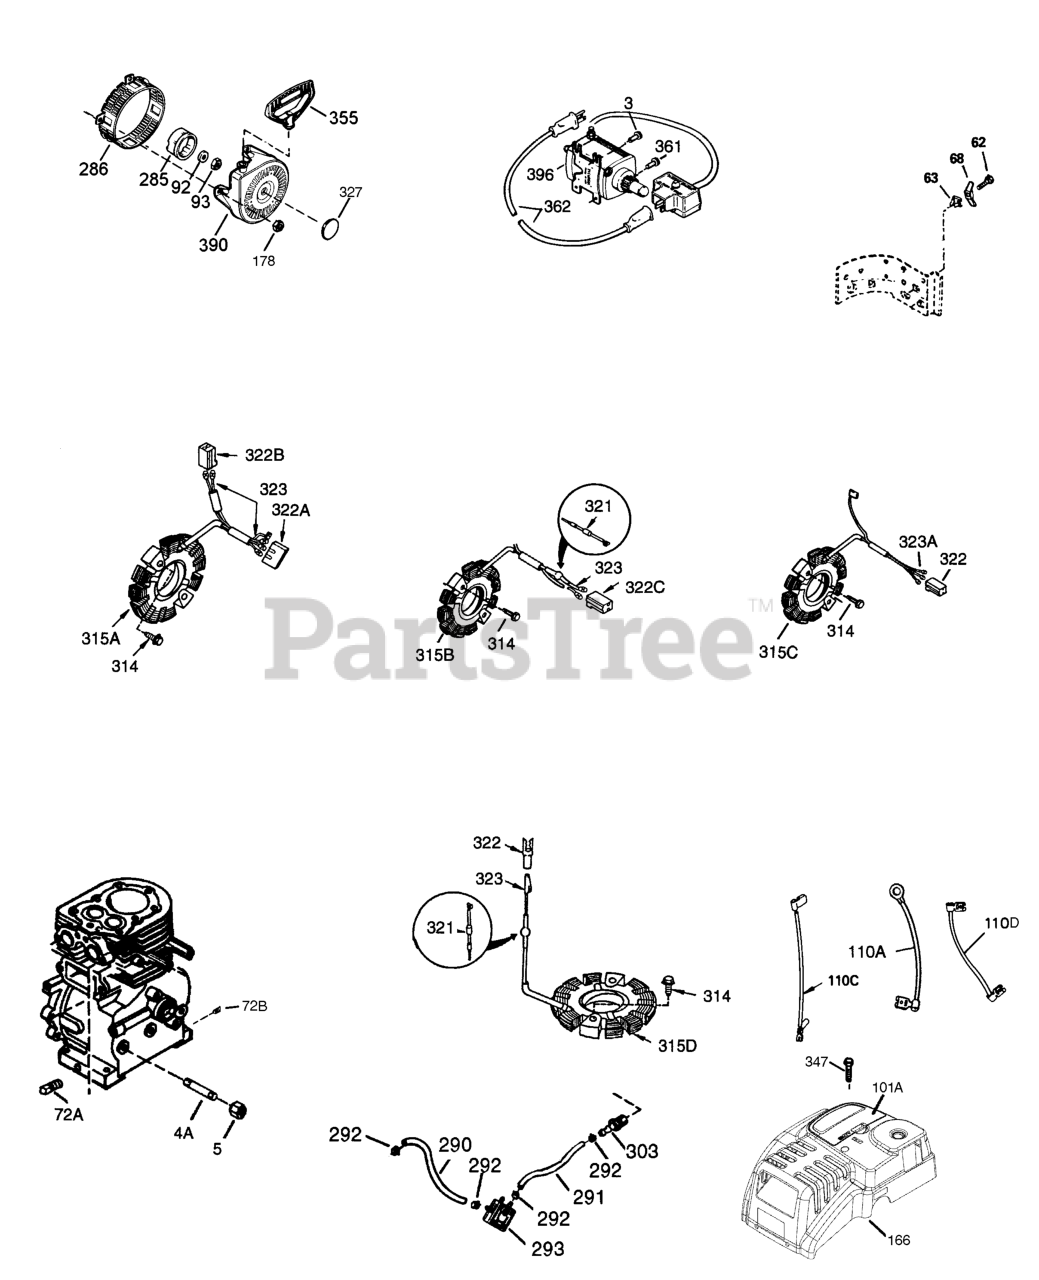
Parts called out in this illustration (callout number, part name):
5	PIPE CAP
41	PISTON ASSY STD
41	PISTON ASSY 010
110A	GROUND WIRE
285	STARTER CUP
291	FUEL LINE
311	DIPSTICK
323	TERMINAL
327	STARTER PLUG
355	START HANDLE
390	STARTER
396	STARTER KIT
999	MAINTENANCE KIT
